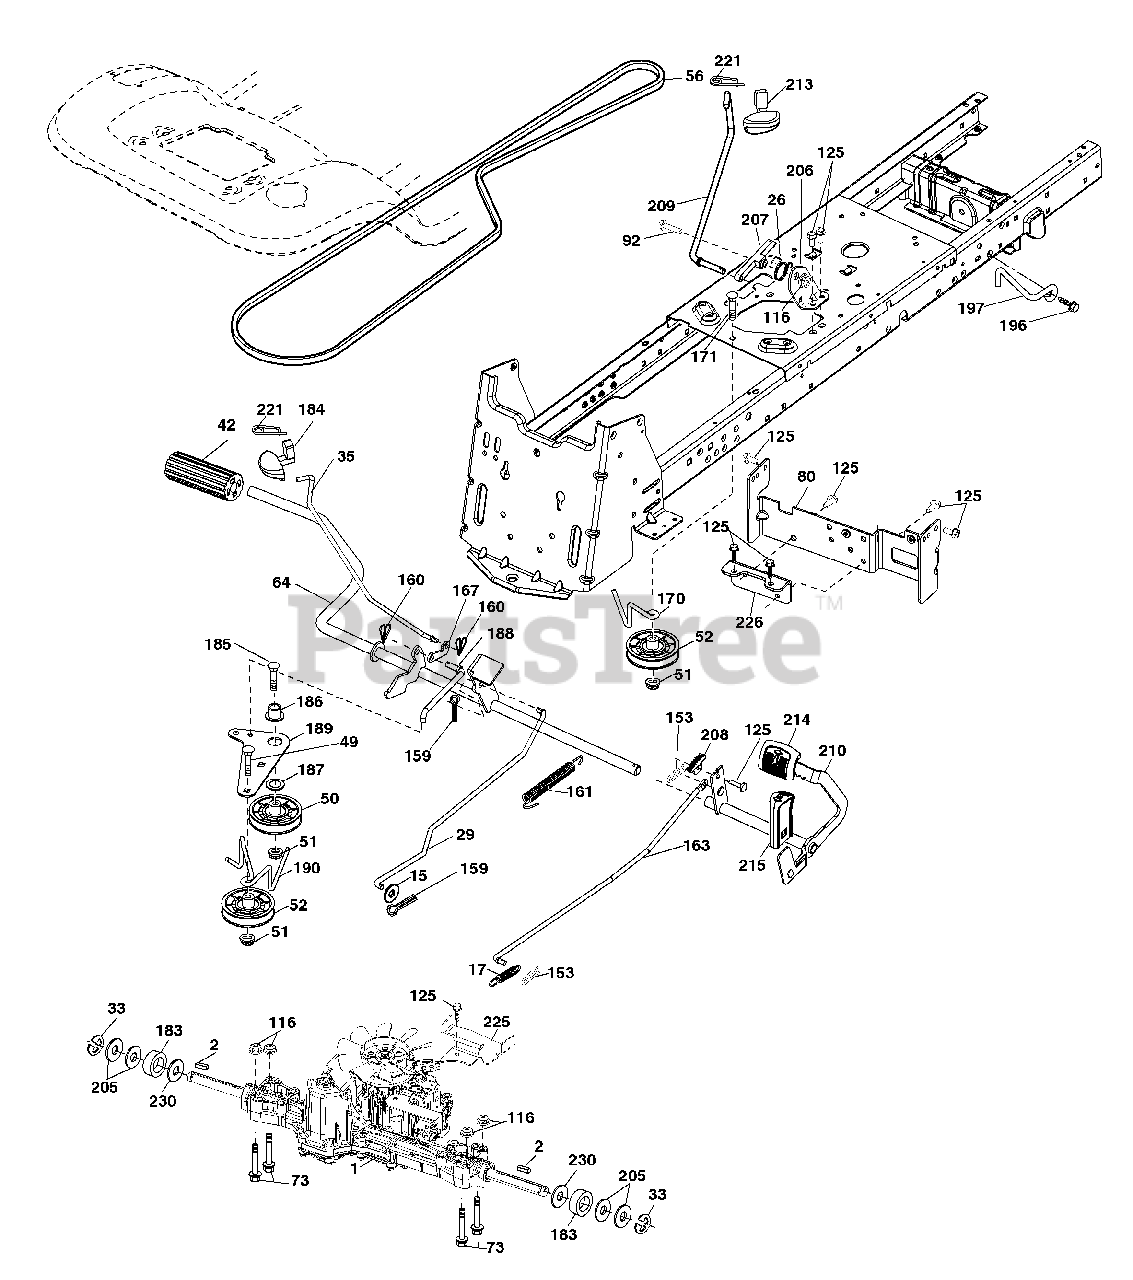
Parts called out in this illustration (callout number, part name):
15	Washer 13/32 x 13/16 x 16 Ga.
17	Spring, Brake
26	Spring Return Cruise
29	Rod, Brake
35	Rod, Brake, Park
42	Cover, Foot Pedal
50	Pulley Idler Flat
51	Lock Nut 3/8-16
52	Idler V-Groove 910" Offset
56	V-Belt, Drive
64	Shaft Asm. Pedal Brake Control
80	Bracket Strap Torque
92	Bolt Fin Hex 5/16-18 unc x 1.25
116	Nut Lock Hex Flange 5/16-18
125	Screw 5/16-18 x 3/4
153	Retainer Spring
159	Pin Cotter 1/8 x 3/4
160	Retainer Clip
161	Spring, Return, Clutch
163	Rod Pedal Control
166	Nut Push .625
167	Latch Brake Parking
170	Keeper Belt Centerspan
171	Bolt RDHD SQNK 3/8-16UNC x 2
183	Spacer Split
184	Handle Parking Brake
185	Bolt Rdhd Sqnk 3/8-16 x 2-1/2
186	Spacer Retainer
187	Washer
188	Link Clutch Ground Drive
189	Bellcrank Ground Drive
190	Keeper Bellcrank Ground Drive
196	Screw 3/8-16 x 1
197	Bracket Clutch Anti-Rotation
206	Bracket Mount Latch Cruise
207	Latch Control Cruise
208	Gear Sector Control Cruise
209	Rod Control Cruise
210	Rocker Asm. Pedal Control
213	Knob Control Cruise
214	Pedal Forward
215	Pedal Reverse
221	Retainer Spring Clip Handle
225	Keeper Belt Trans.
226	Bracket Mount Touque
230	Washer Hardened
